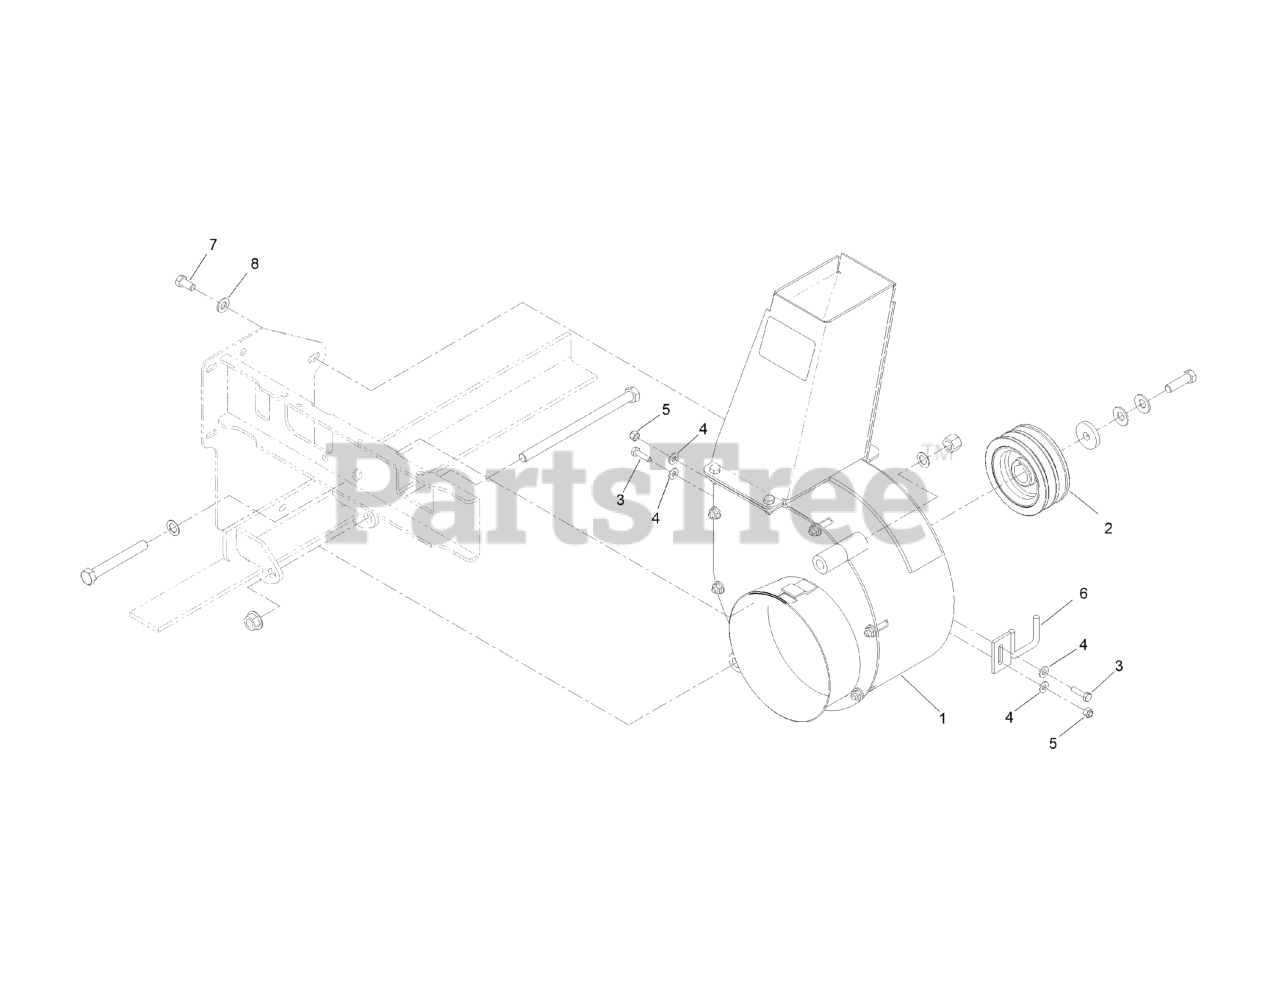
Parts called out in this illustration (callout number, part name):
1	BLOWER ASM
3	SCREW-HH
4	WASHER-FLAT
5	NUT-LOCK, NI
7	SCREW-HH
8	WASHER-FLAT
